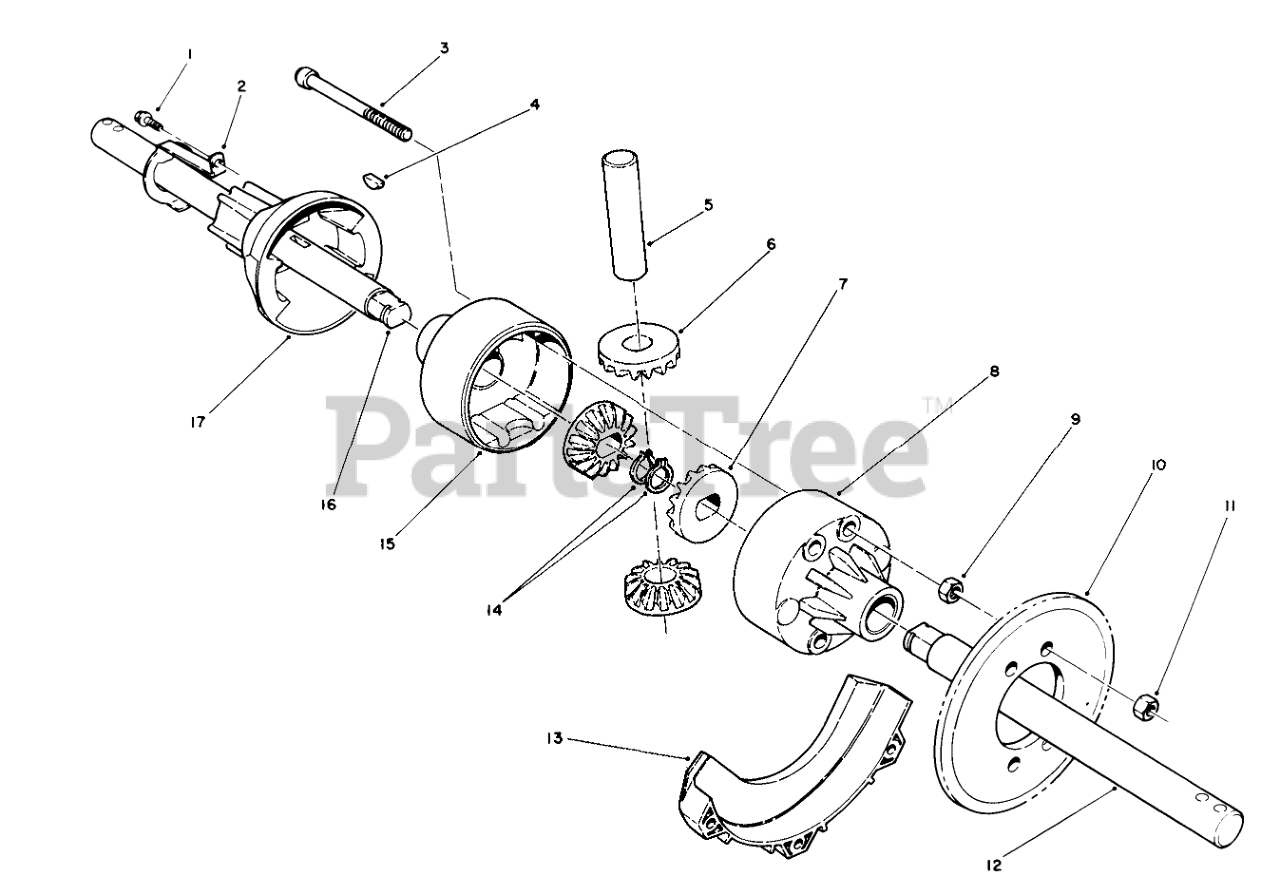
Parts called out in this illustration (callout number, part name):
1	SCREW-HWH
2	SPRING-LOCKOUT
3	SCREW-HSH
4	KEY-WOODRUFF
5	Shaft-Cross
6	Gear-Cross Shaft Pinion
7	Gear-Side Pinion
8	HOUSING ASSY - FEMALE
9	NUT-HEX
10	SPROCKET-27T
11	NUT-LOCK, NI
12	SHAFT - DIFFERENTIAL,LH
13	GUARD-CHAIN
14	RING-RETAINING
15	HOUSING ASSY - MALE
16	SHAFT - DIFFERENTIAL,RH
17	COUPLING-DIFFERENTIAL
